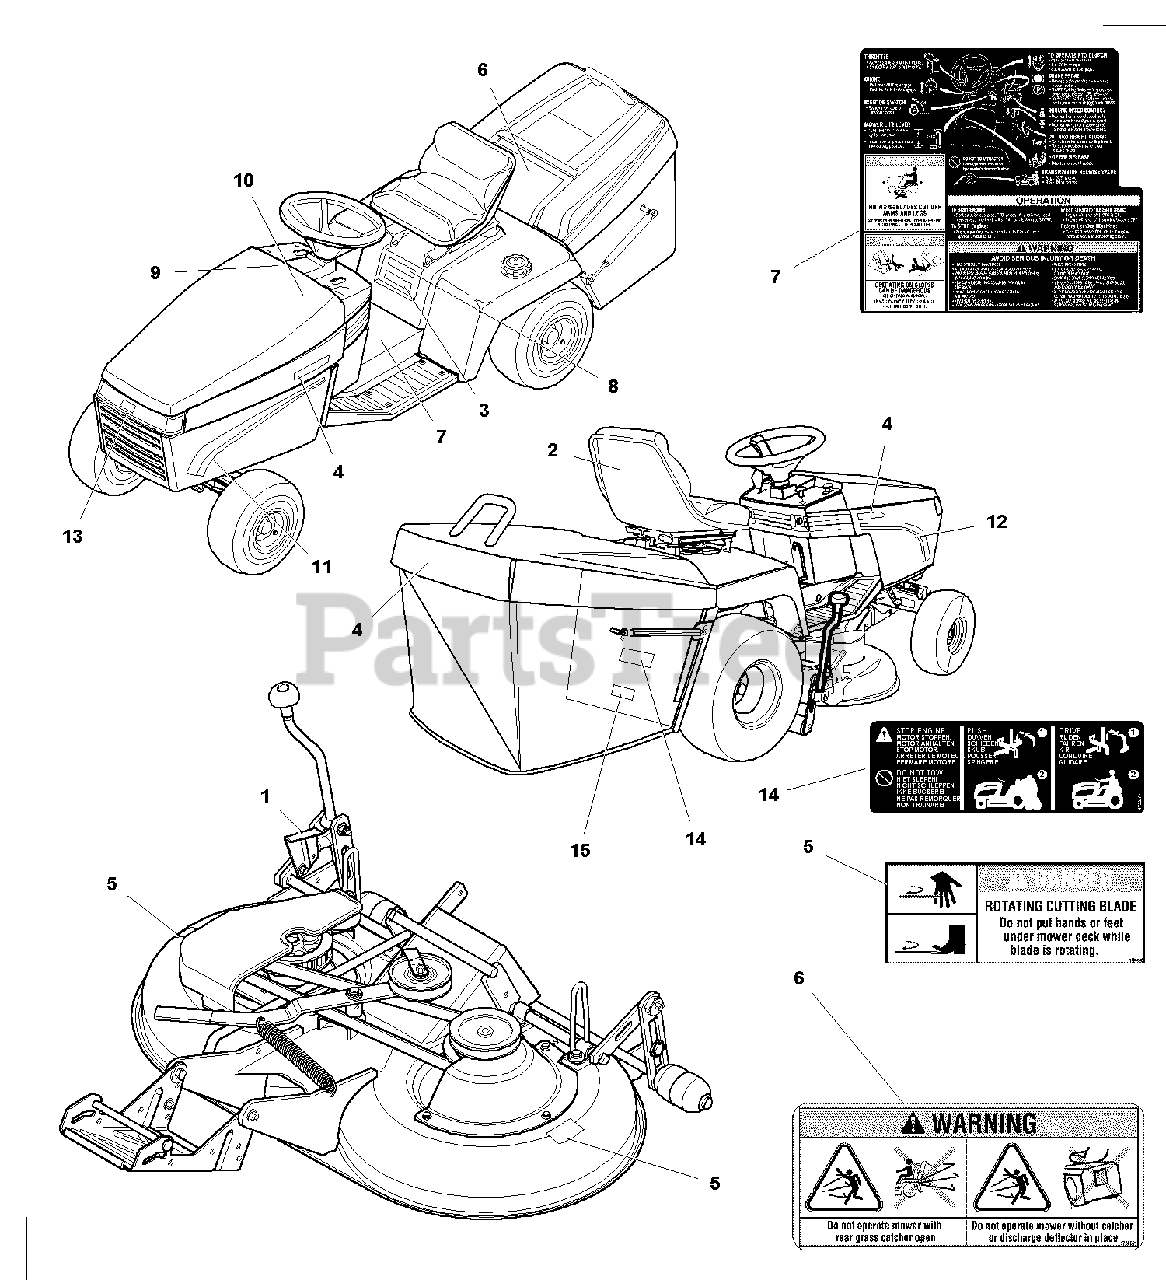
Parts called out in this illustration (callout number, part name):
1	DECAL, Cutting Height
2	DECAL, Logo, USA
3	DECAL, Engine, 18V-Twin
4	DECAL, Simplicity w/Logo, Fuel Resistant
5	DECAL, Danger, Rotating Blades
6	DECAL, Danger, Catcher Open
7	DECAL, Operating Instructions
8	DECAL, Baron
9	DECAL, Touch Up Paint
10	DECAL, Drive Belts/Mower Blades
11	DECAL, Hood Stripe L H
12	DECAL, Hood Stripe R H
13	DECAL, Simplicity Logo
14	DECAL, Transmission Release Valve
15	DECAL, Draw Bar
